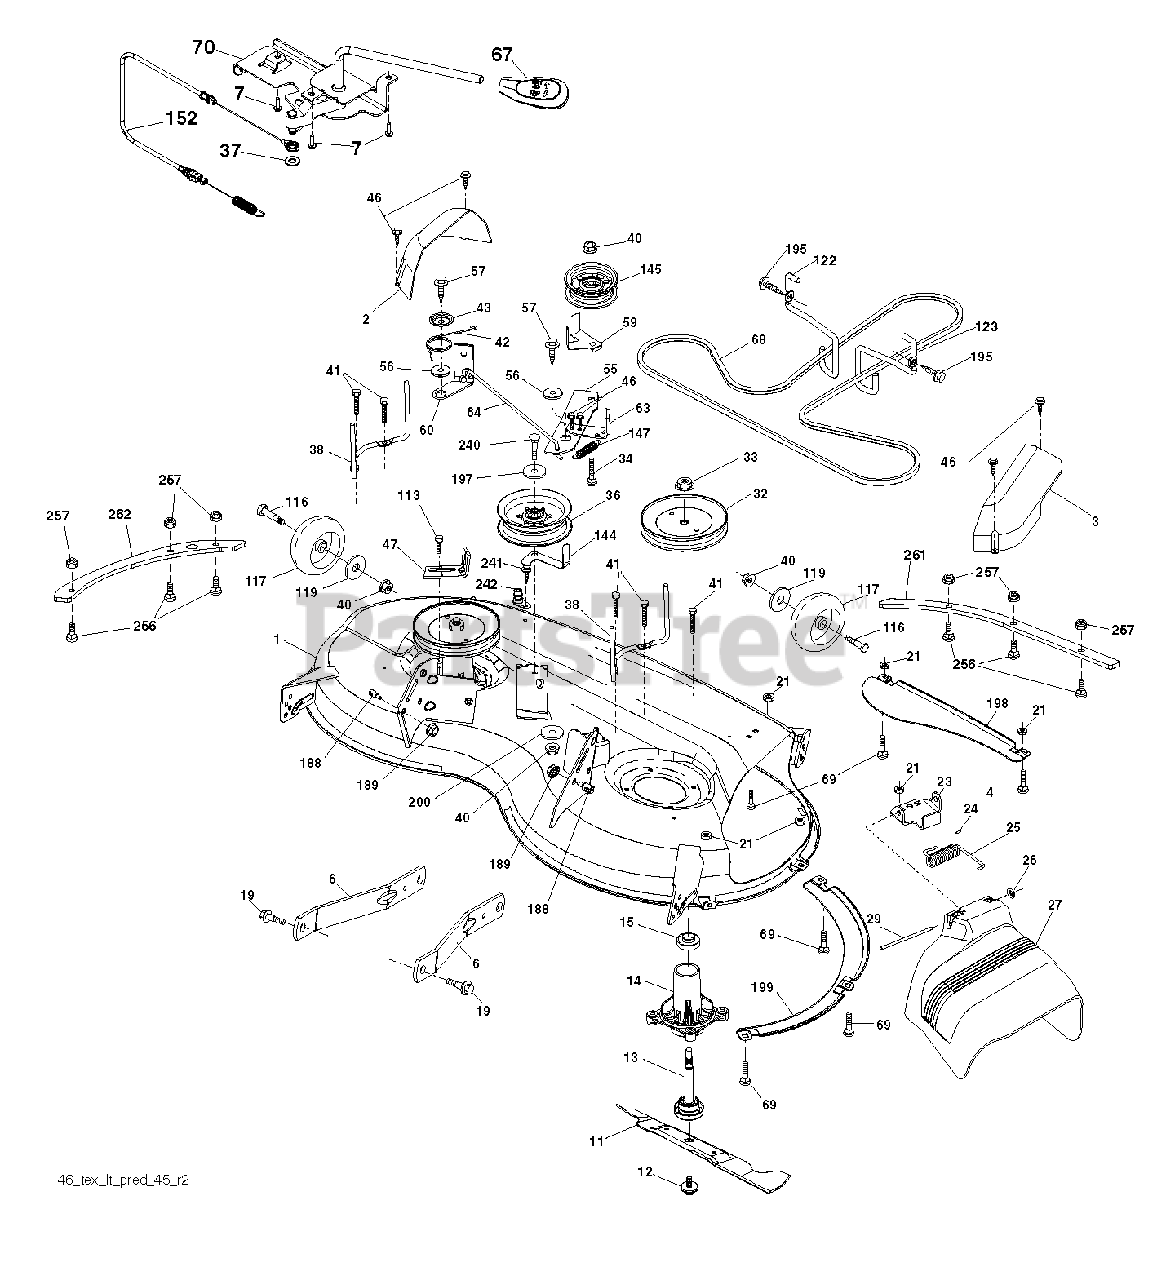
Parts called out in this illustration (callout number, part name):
1	DECK SVC 46"
2	COVER.MANDREL.LH.46"
3	COVER.MANDREL.RH.46"
4	BOLT
6	ARM.SUSPENSION.MOWER.R
7	SCREW.#10 X 0.750.BOS
11	BLADE.MOWER.46".HI.LIFT
12	SCREW.SEMS.7/16-20X1.HEX.HEAD
13	SHAFT ASM.MNDRL.N/GREASEABLE
14	HOUSING.MANDREL.4PT.
15	BEARING.MANDREL.TOP.EXTENDED
19	BOLT.SHOULDER
21	LOCKNUT
23	BRKT.DEFLECTOR.38"2005+
24	CAP-SLEEVE LT
25	SPRING.TORSION.DEFLECT
26	NUT PUSH M
27	SHIELD.DEFLECTOR.MOWER.46"BLAC
29	ROD.HINGE
32	PULLEY.MANDREL.5.438.PD
33	NUT.FLANGE.LOCK.TOP
34	BOLT.3/8-16X1.50
36	PULLEY.IDLER.2006
37	WASHER
38	KEEPER.BELT.MANDREL.PULLEY
40	NUT LOCK FLG 3/8-16 UNC
41	BOLT.HEX.WASHR.HED.313-18X1.19
42	SPRING.TORSION.BRAKE
43	SRPING.TORSION.RETAINE
46	SCREW.1/4-20X5/8
47	BRKT.CLUTCH.CABLE
56	SPACER.RETAINER
57	SCREW 3/8-16X1
59	GUARD, BELT
60	ARM BRAKE MOWER RH 38"
63	ARM BRAKE MOWER
64	LINKAGE BRAKE
67	HANDLE.CLUTCH.CABLE.LT
68	V-BELT
69	BOLT
70	CLUTCH.ASM.MANUAL.YT.PREDATORQ
113	BOLT.5/16HEX.WHS.HD
116	BOLT.SHOULDER.3/8-16X3-5/8.
117	WHEEL. GUAGE RALLY
119	WASHER
122	KEEPER BELT ENGINE LH
123	KEEPER BELT RH
144	KEEPER.BELT.MOWER
145	PULLEY.IDLER.48"PRIMARY
147	SPRING RETURN
152	CABLE.MECHANICAL.CLUTCH
188	STUD.FASTNER.W/ANTI-ROTATE
189	NUT LOCK HEX FLANGE 5/16-18
195	SCREW, 3/8-16X3/4
197	WASHER
198	BAFFLE CENTER FRONT
199	BAFFLE FRONT RH
200	WASHER.13/32 X 1 X 1/2.11GUARD
240	BOLT-HEX EAK
241	SCREW.TT.#10-32X.5.3/8.FLANGE
242	PORT.WASHOUT
256	SCREW.BUTTONHEAD.1/4-20X1
257	NUT T
261	PLATE.REINFORCE.46.BOLT.ONX431
262	PLATE.REINFOR.46.SIDEBOLT.X431
